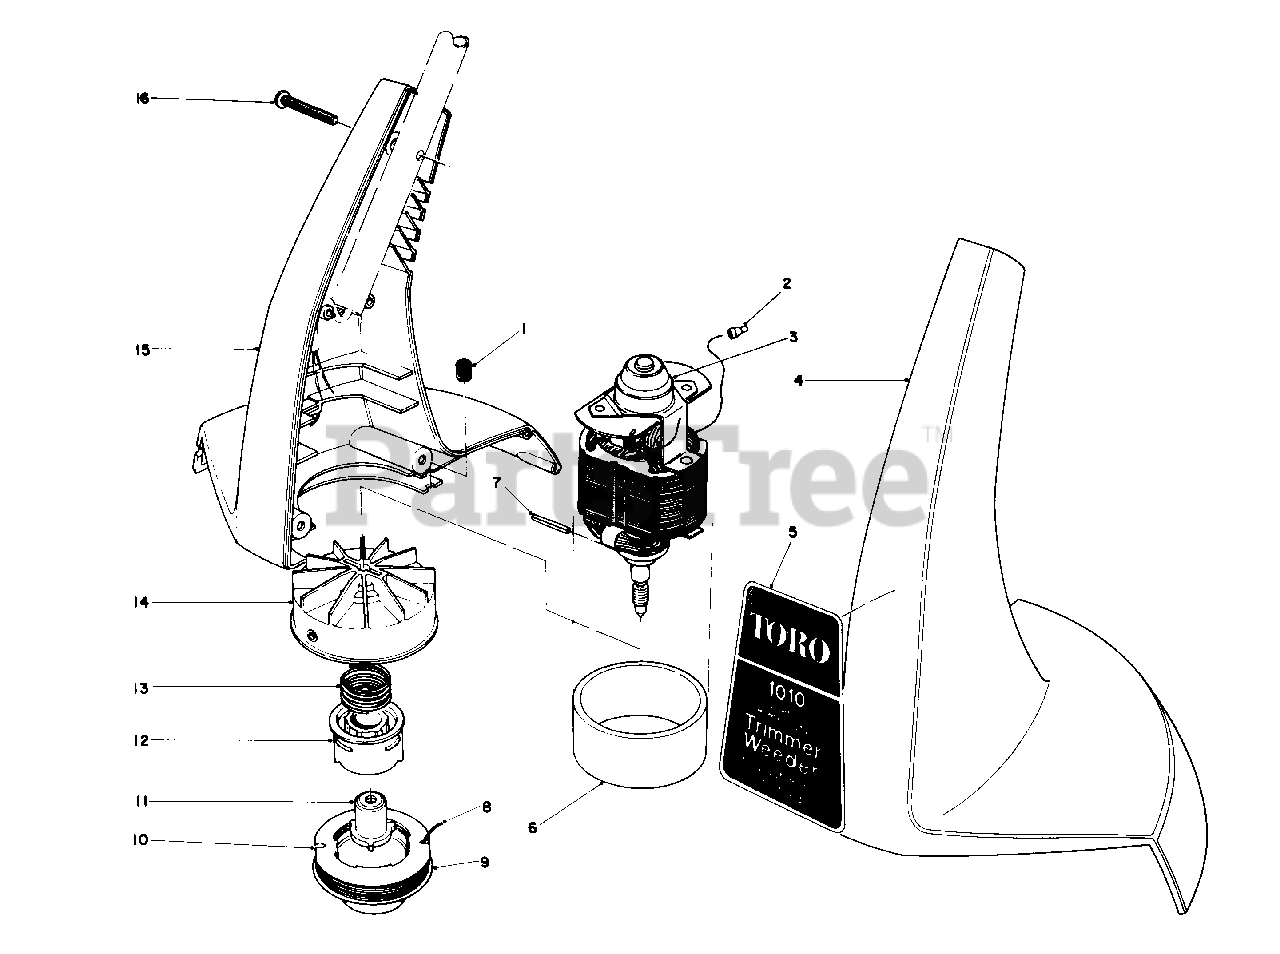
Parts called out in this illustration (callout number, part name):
2	Electric Connector
4	Housing-L.H.
5	Decal-Housing
6	Dampening Sleeve
8	30' Coil-.050 Cutting Line In Spool
9	Spool Cap
10	30', .050 Dia. Cutting Line Prewound On Spool
11	Driver-Detent
12	Spool Core
13	Spring-Compression
14	Fan Hub Assembly
15	Housing Assembly, R.H.
16	Cross Recess Pan Hd.Thread Forming Screw
